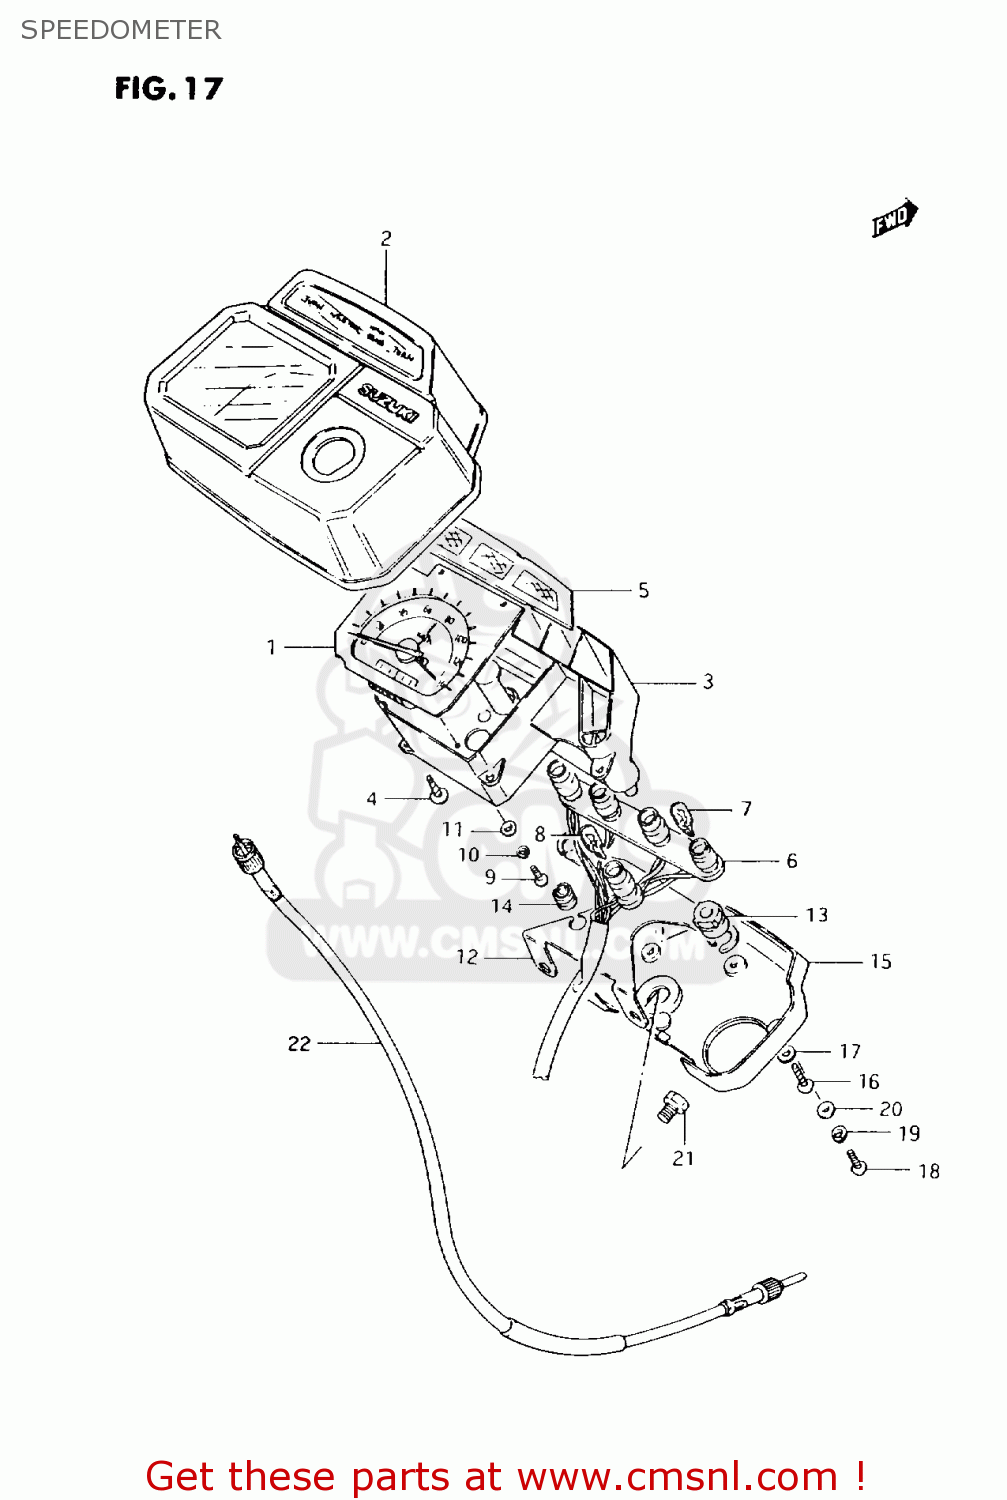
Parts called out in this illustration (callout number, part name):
1	SPEEDOMETER(KILO)
2	HOOD,METER
3	CASE,METER
4	SCREW
5	PLATE,PILOT LENS
6	SOCKET
7	BULB(6V,3W)
8	BULB(6V1.7W,STANLEY,A61A)
9	SCREW
10	WASHER,LOCK
11	WASHER
12	BRACKET,METER
13	CUSHION,METER
14	CUSHION
15	COVER,LWR
16	SCREW
17	WASHER
18	SCREW
19	WASHER,LOCK
20	WASHER
21	BOLT
22	CABLE ASSY,SPEEDOMETER
